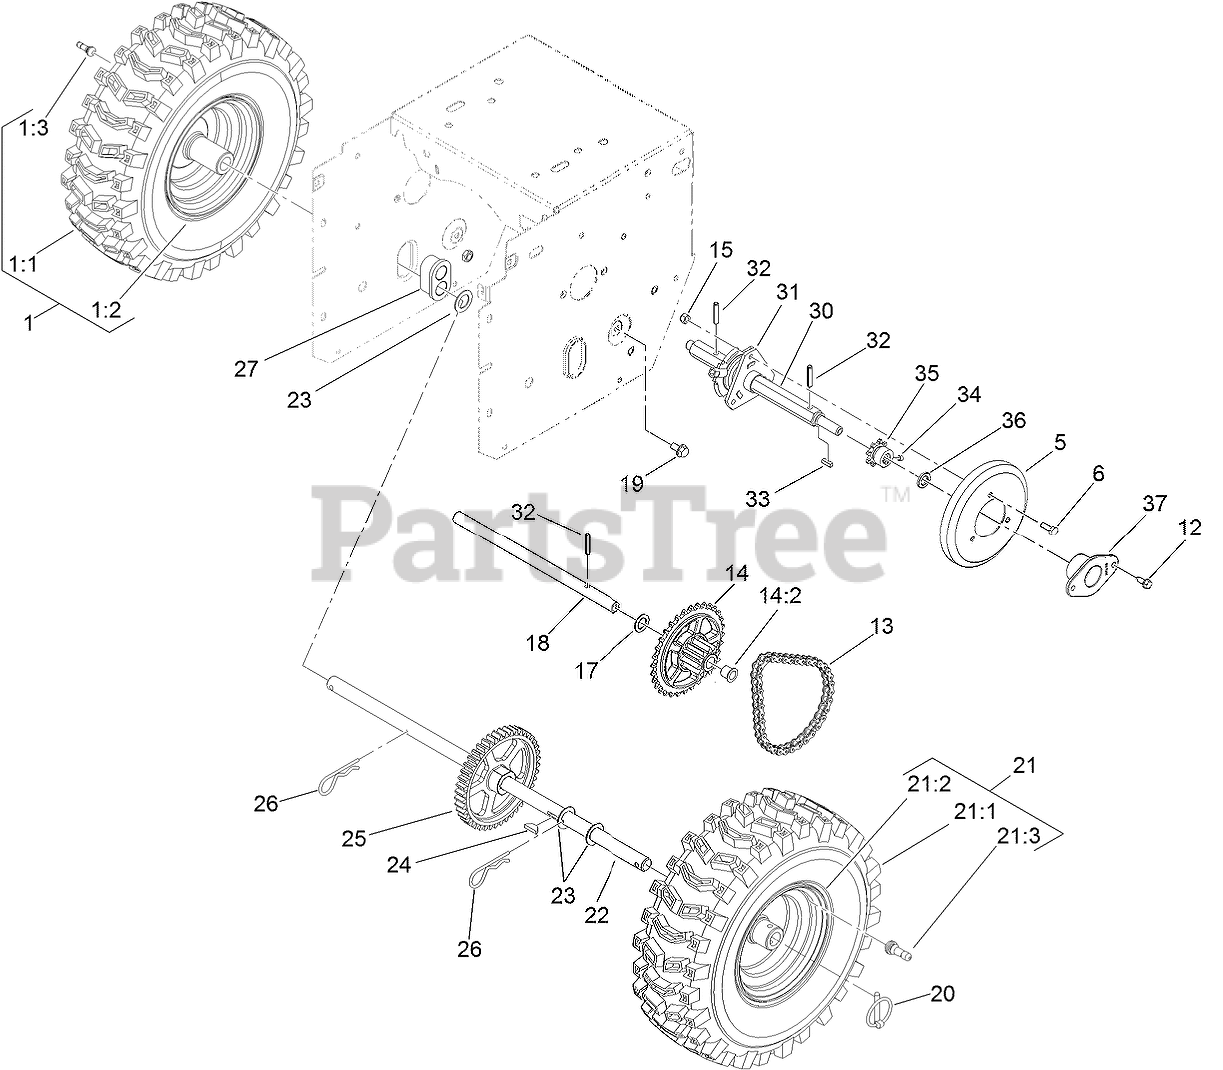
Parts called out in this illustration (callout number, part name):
1	RH WHEEL AND TIRE ASM
1:2	RIM-TIRE
1:3	STEM-VALVE
5	WHEEL-FRICTION
6	SCREW-HH
12	SCREW-HWH
13	CHAIN-ROLLER
13	LINK-CONNECTING
14	SPROCKET ASM
14:2	BUSHING-FLANGE
15	NUT-LOCK, NI
17	WASHER-FLAT
18	SHAFT-INTERMEDIATE
19	SCREW-HWHTF
20	KLIK PIN ASM
21	LH WHEEL AND TIRE ASM
21:2	RIM-TIRE
21:3	STEM-VALVE
22	SHAFT-AXLE
23	WASHER-THRUST
24	KEY-WOODRUFF
25	GEAR-AXLE, 44 TOOTH
26	PIN-HAIR
27	BEARING-AXLE
30	SHAFT-HEX
31	TRUNNION-HEX
32	PIN-ROLL, SLOTTED
33	KEY-SQUARE
34	SCREW-HSH
35	SPROCKET-8 TOOTH
36	SPACER-BUSHING
37	RETAINER-BEARING
